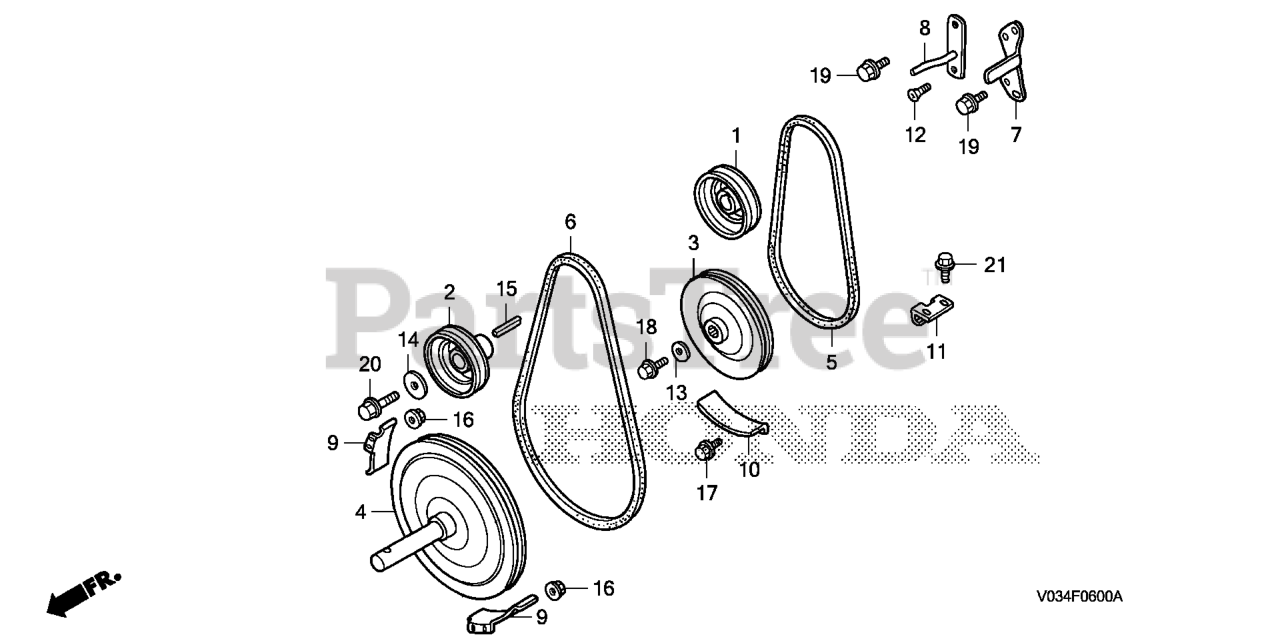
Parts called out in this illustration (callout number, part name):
1	PULLEY, WHEEL DRIVEN
2	PULLEY, AUGER DRIVE
3	PULLEY, WHEEL DRIVEN (133MM)
4	PULLEY, AUGER DRIVEN (198MM)
5	V-BELT (SA-29)
6	V-BELT (SB-35)
7	STOPPER, R. BELT (L. SIDE)
8	STOPPER, L. BELT (R. SIDE)
9	STOPPER, AUGER BELT
10	PROTECTOR, BELT (WHEEL)
11	GUIDE, BELT
12	BOLT, DOOR LOCK STRIKER
13	WASHER, CAMSHAFT SIDE
14	WASHER, LOCK (8MM)
15	KEY (7X7X33)
16	NUT, FLANGE (6MM)
17	BOLT, FLANGE (6X12) Use up to Engine SN 1543277.
18	BOLT, FLANGE (6X16)
19	BOLT, FLANGE (8X16) Use from Engine SN 1000016.
20	BOLT, FLANGE (8X28)
21	BOLT, FLANGE (6X12) Use up to Engine SN 1543277.
